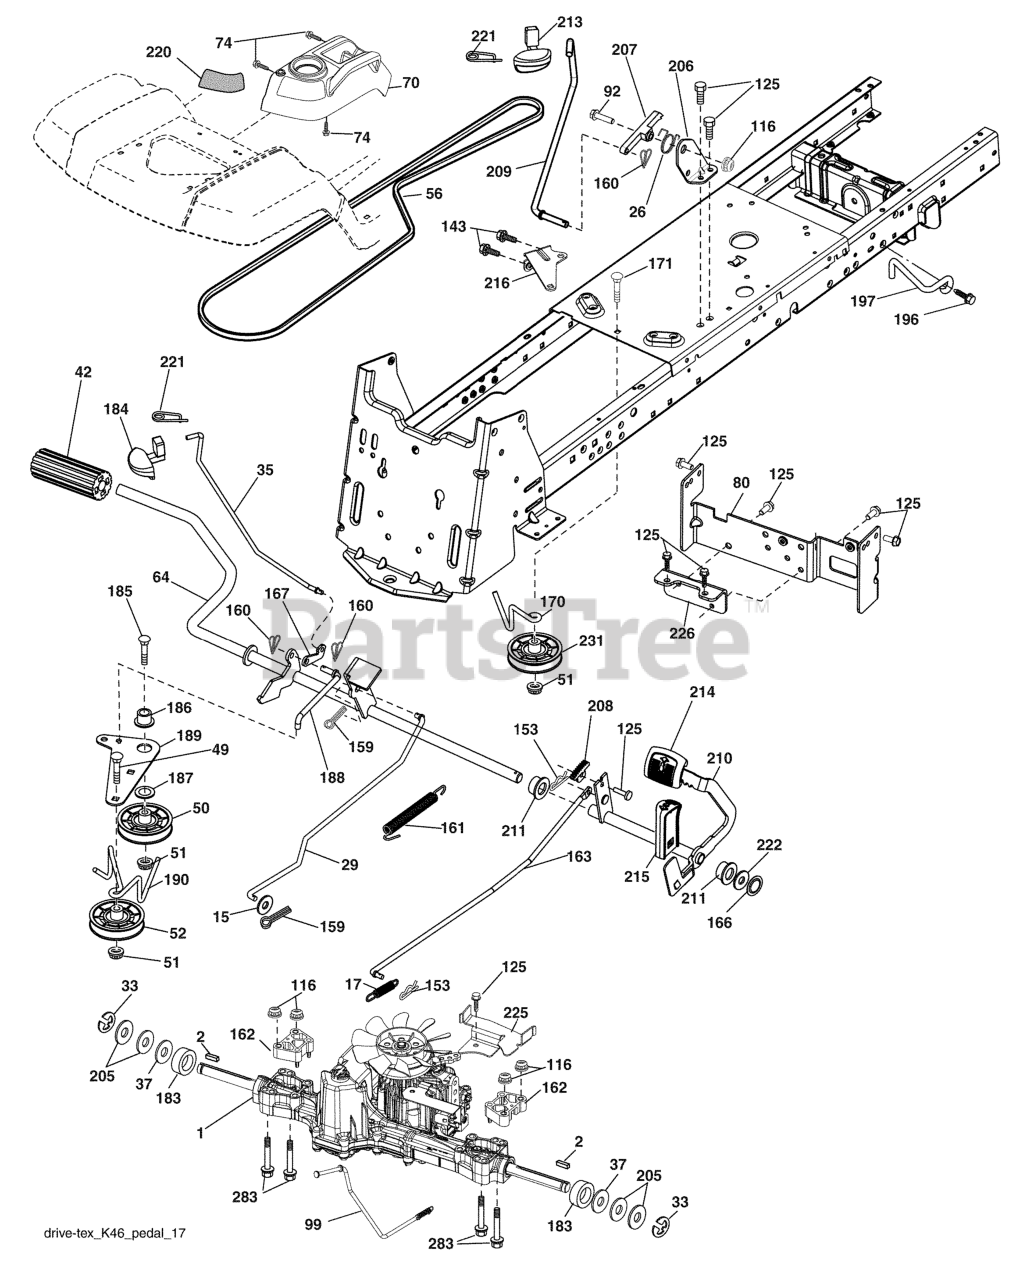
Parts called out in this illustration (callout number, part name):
1	TRANSAXLE, TUFFTORQ K46
2	SQUARE KEY
15	WASHER
17	SPRING.BRAKE.K46.GREEN
26	SPRING.RETURN.CRUISE
29	ROD.BRAKE.K46
35	ROD.BRAKE.PARKING.GT.H
37	WASHER.HARDENED
42	PEDAL COVER T
50	IDLER.FLAT.910.OFFSET
51	NUT LOCK FLG 3/8-16 UNC
52	IDLER.V-GROOVE.910.OFFSET
56	V-BELT.MOWER.92.40.42/K46
64	SHAFT.ASM.PEDAL.BRK.CNTR
70	RP CONSOLE.ASM.PCH.W/TB
74	SCREW.HI-LO.CONSOLE
80	STRAP TORQUE
92	BOLT
99	ROD.SPRING.BYPASS.K46.TEX.GT
116	NUT LOCK HEX FLANGE 5/16-18
125	SCREW
143	Screw Thdrol 5/16-18 x 1/2
153	RETAINER M
159	COTTER PIN
160	RETAINER CLIP
161	SPRING, RETURN LT
162	SPACER TRANS
163	ROD.CONTROL.PEDAL.K46
166	NUT.PUSH.625.2006
167	LATCH.BRAKE.SPRING
170	KEEPER.CENTER SPAN.1.688
183	SPACER AXLE
184	HANDLE.PARKG.BRK.HUSQ X667
185	BOLT
186	SPACER.RETAINER
187	WASHER 12/32X2X10GA
188	RP.LINK.CLUTCH.GROUND.DRIVE
189	BELLCRANK.GROUND.DRIVE.TEX.
190	KEEPER.BELLCRANK.DRIVE
196	SCREW 3/8-16X1
197	BRKT.ANIT-ROTATION.CLUTCH
206	BRKT.MOUNT.LATCH.CRUIS
207	LATCH.CONTROL.CRUISE
208	GEAR.SECTOR.CONTROL.CR
209	ROD.CONTROL.CRUISE.GT.
210	ROCKER.ASM.PEDAL.CONTR
211	BEARING.NYLON
213	KNOB.CONTROL.CRUSIE.HU
214	PEDAL.FORWARD.TEX.GT.4
215	PEDAL.REVERSE.TEX.GT.4
216	BRACKET.PULLEY.IDLER.W/TEX
220	REFLECTOR.RH.TEX GT
221	RETAINER.SPRING.CLIP.H
222	WASHER 21/32 X 1-1/4 X 10 GA.
225	KEEPER.BELT.TRANSAXLE.K46
226	BRACKET.MOUNT.TORQUE.K46.TLT
231	IDLER.V-GROOVE.1.688.OFFSET
283	HEX BOLT, 5/16-18 X 4.25 GR. 5
